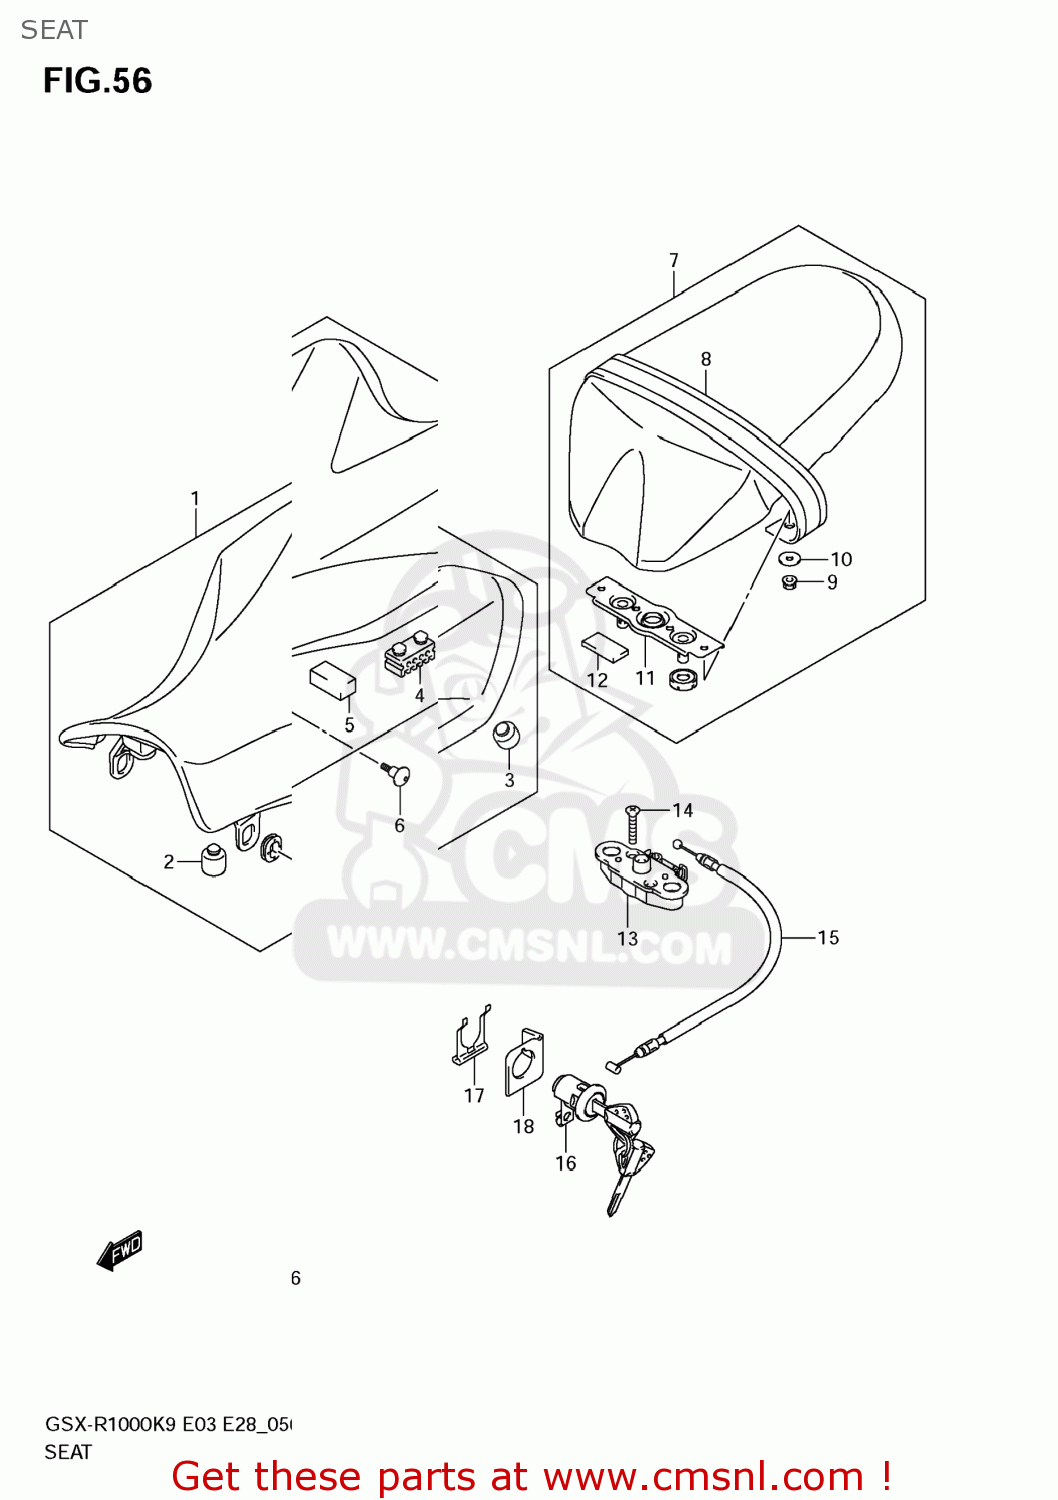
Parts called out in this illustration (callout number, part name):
1	BUDDYSEAT
2	CUSHION
3	CUSHION
4	CUSHION,SIDE
5	CUSHION,FR(20X40X15)
6	SCREW(6X20)
7	DUOZIT
8	BAND ASSY,SEAT(BLACK)
9	NUT
10	WASHER(6.5X20X1.6)
11	STRIKER
12	CUSHION,FR(20X40X15)
13	BRACKET,SEAT SUPPORT
14	SCREW
15	CABLE,SEAT LOCK
16	LOCK SET,SEAT
17	PLATE,SEAT LOCK ASSY
18	GUIDE,SEAT LOCK CABLE
